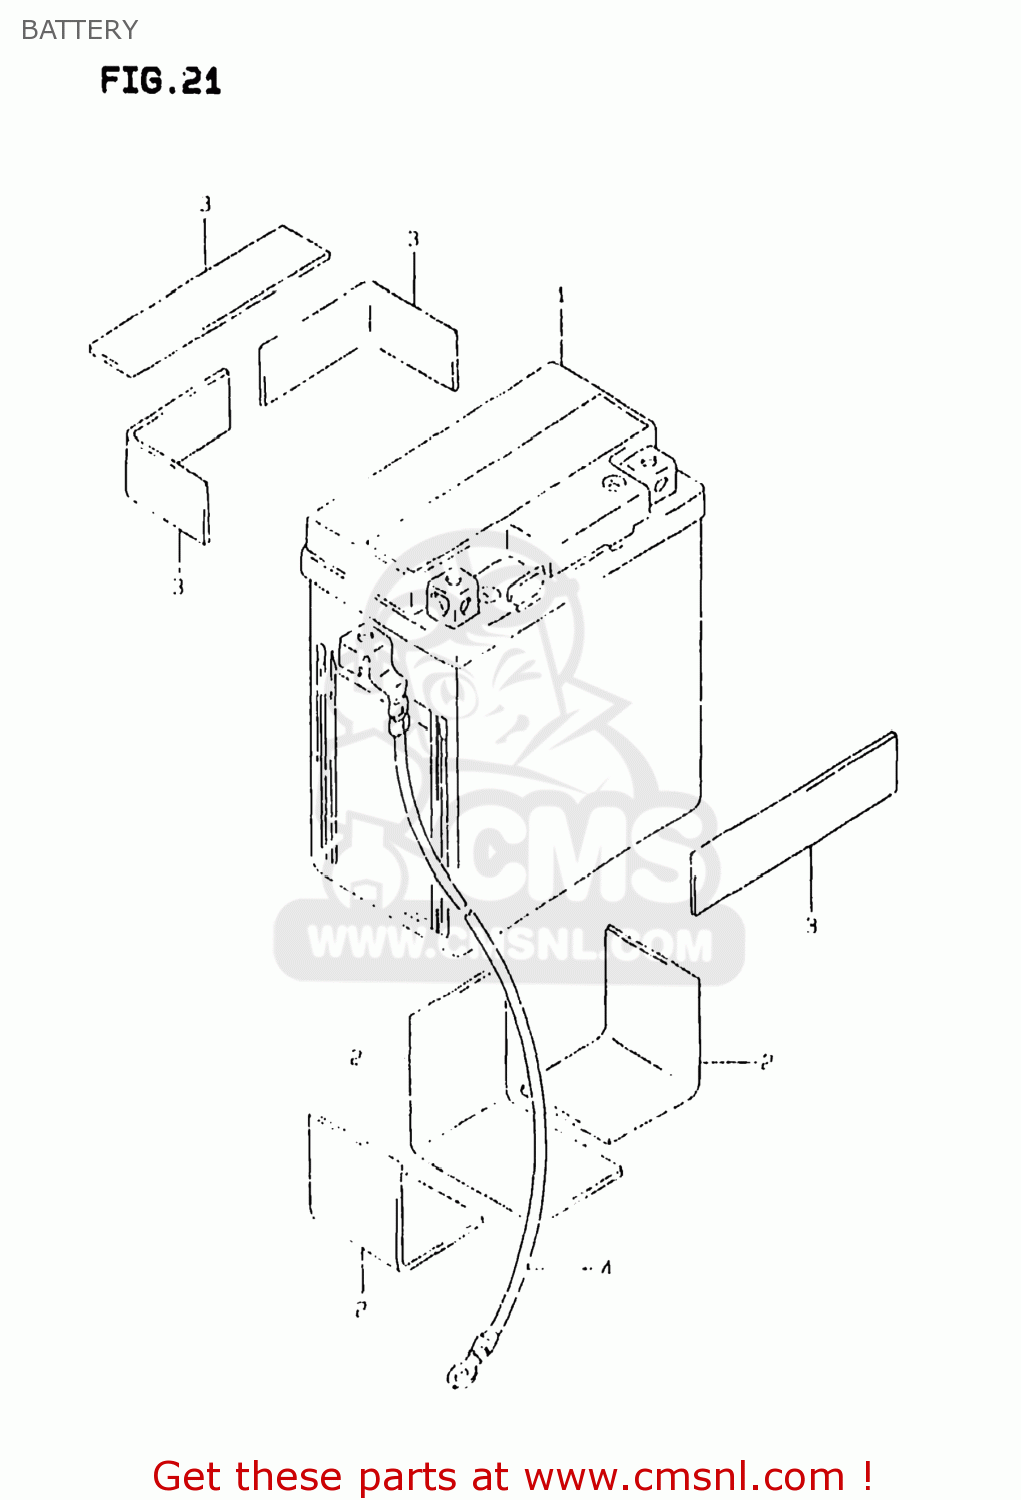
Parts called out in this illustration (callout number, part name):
1	BATTERY ASSY(YTX7L-BS,12V6AH)
2	PROTECTOR(170X95X3.0)
3	PROTECTOR(170X95X3.0)
4	WIRE,BATTERY MINUS LEAD
